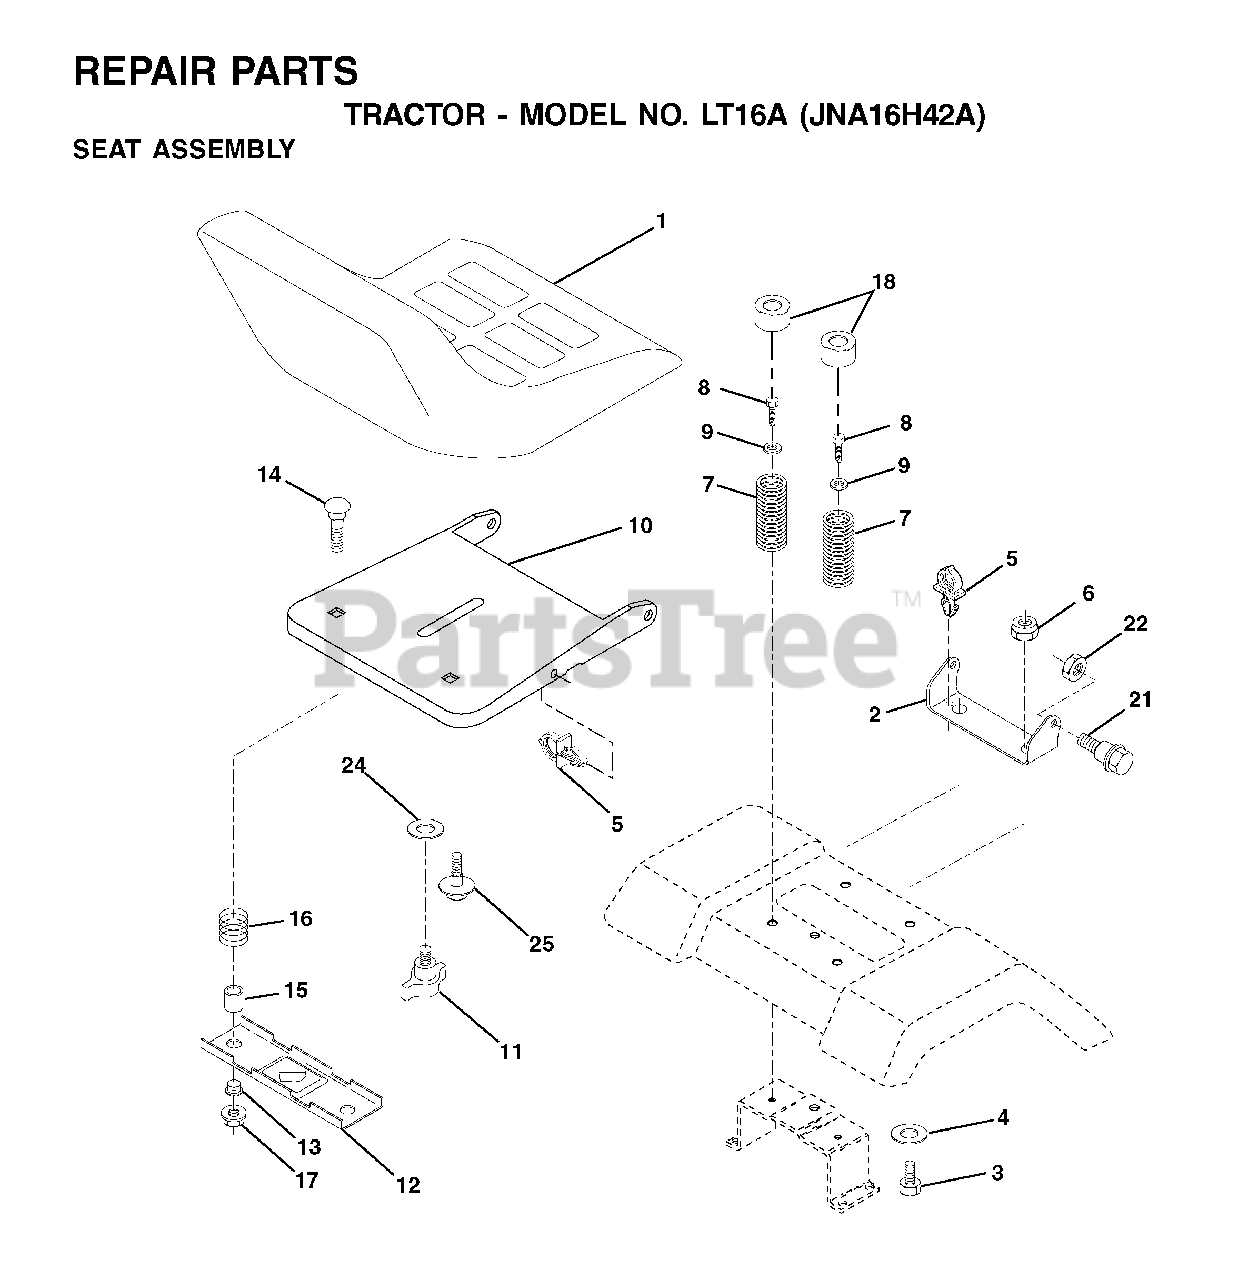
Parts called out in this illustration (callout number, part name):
2	SEAT PIVOT BRKT
4	WASHER PM
5	PUSH CLIP
6	NUT
7	SPRING COMPRESSION
8	SCREW 3/8-16X1
9	WASHER
10	PAN, SEAT
11	KNOB.SEAT.ADJ.WINGNUT
12	BRKT SWITCH
14	BOLT.ROUND.HEAD.SQUARE.NECK
15	SPACER SPLIT
16	SPRING COMPRESSED
17	NUT T
18	CAP SPRING
21	BOLT.SHOULDER.5/16-18
22	NUT.71038.31-18.HEX.NYLOCK
25	BOLT,SHOULD
